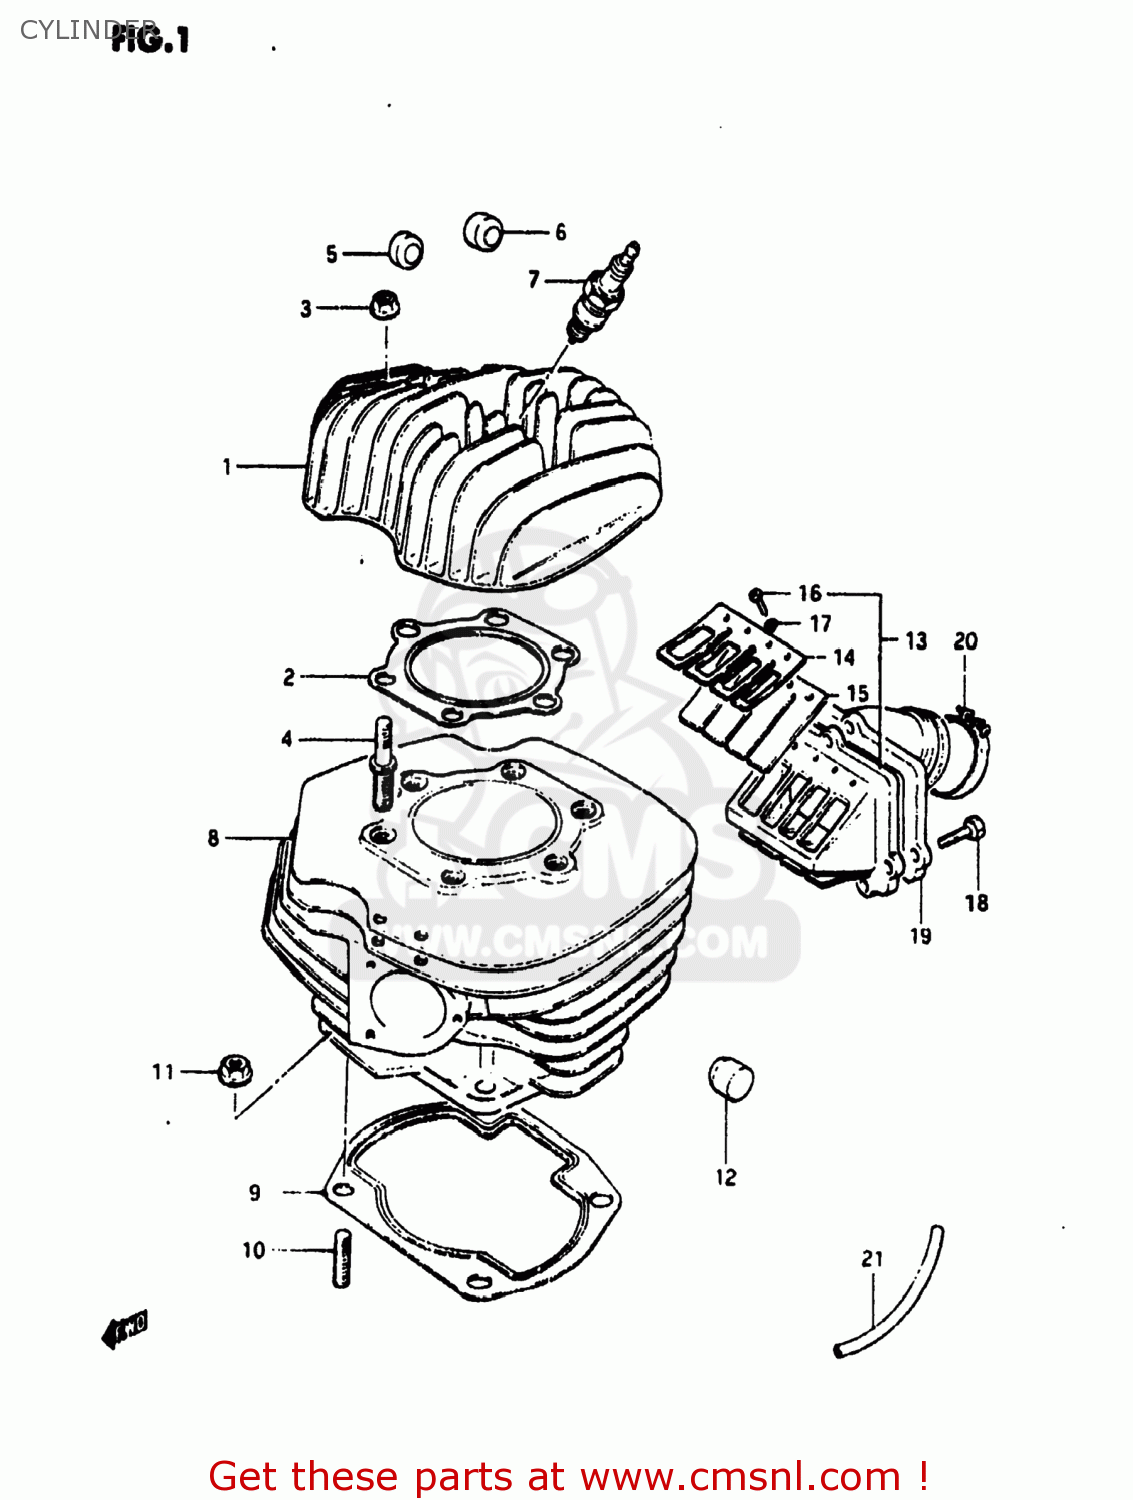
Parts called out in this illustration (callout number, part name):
1	HEAD,CYLINDER
2	GASKET,CYLINDER HEAD (NAS)
3	NUT
4	BOLT,STUD
5	PAD,CYLINDER
6	PAD,CYLINDER HEAD
7	PLUG,SPARK(NGK B-8EN)
8	CYLINDER
9	GASKET,CYLINDER (MCA)
10	STUD 10X30
11	NUT
12	PAD,CYLINDER HEAD
13	STOPPER,REED VALVE
14	STOPPER,REED VALVE
15	VALVE,REED
16	SCREW
17	LOCK WASHER
18	BOLT
19	PIPE,INTAKE
20	CLAMP
21	HOSE
